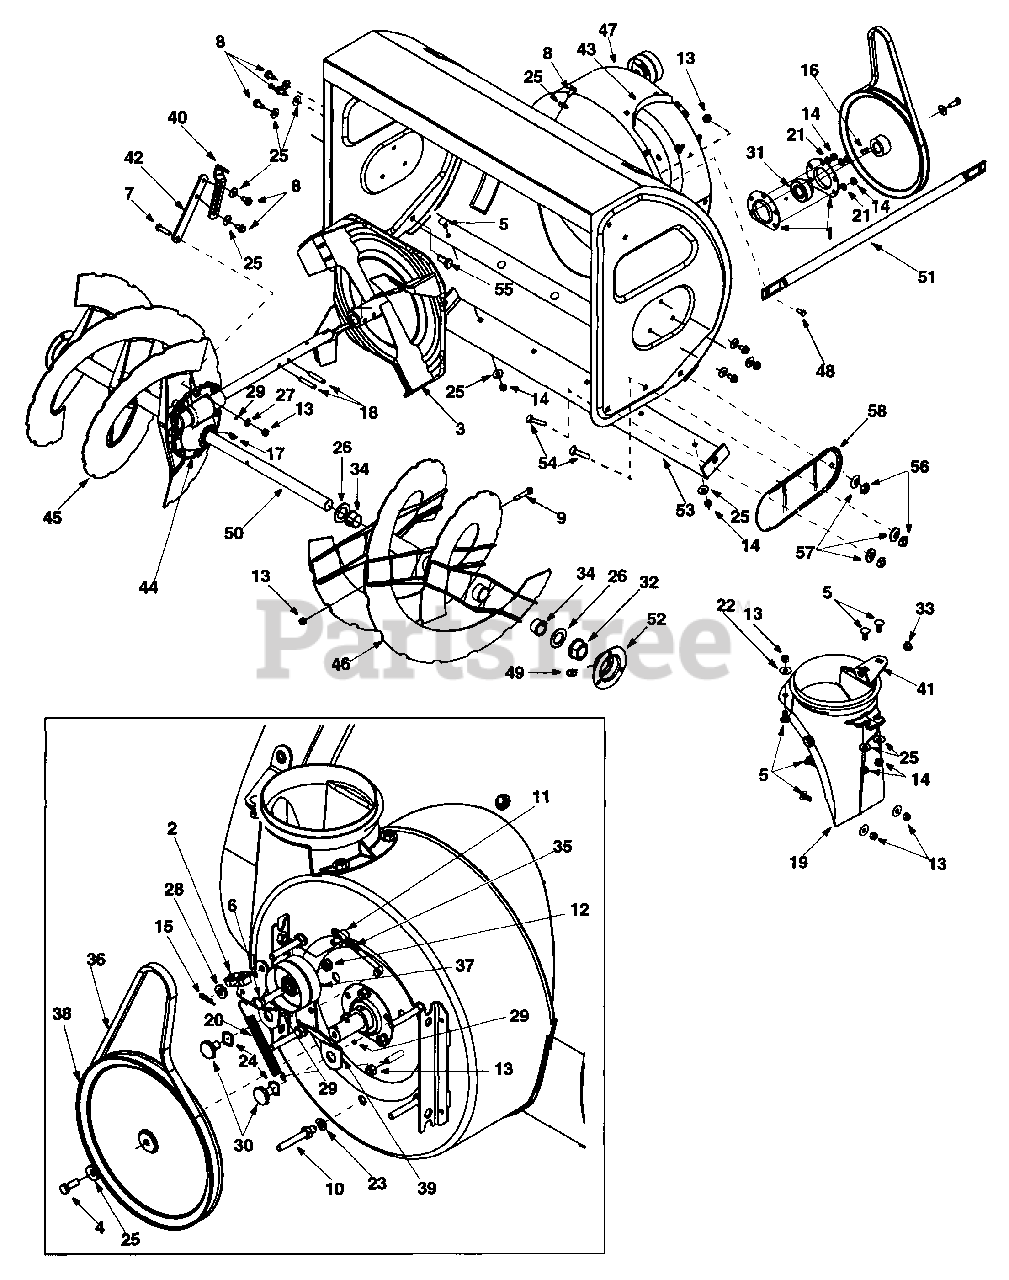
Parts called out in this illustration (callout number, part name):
1	Bearing Housing
2	Bracket Assembly: Auger Break
3	Impeller Assembly: 16"
4	Hex Lock Bolt 5/16-18 x .875"
5	Carriage Bolt 5/16-18 x .750"
6	Hex Screw, Special 3/8-24 x 1.5"
7	Hex Screw 5/16-18 x 1.25"
8	Self-Tapp. Screw 5/16-18 x .625"
9	Shear Bolt 5/16-18 x 1.75"
10	Stud
11	Ferrule
12	Jam Nut 3/8-24
13	Hex Lock Nut 5/16-18
14	Hex Nut 5/16-18
15	Hairpin Clip
16	Key
17	Key
18	Spiral Pin
19	Chute Adapter
20	Extension Spring
21	Lock Washer
22	5/16 Washer
23	Lock Washer
24	Wave Washer
25	Beleville Washer
26	Flat Washer
27	Spring Washer
28	Flat Washer
29	Grease
30	Shoulder Screw
31	Self-Aligning Bearing
32	Flange Bearing w/ Flats
33	Plastic Bushing
34	Flange Bushing
35	Idler Rod: Auger
36	V-Belt
37	Flat Idler
38	Pulley
39	Idler Bracket: Auger
40	Support Bracket
41	Chute Crank Bracket
42	Support Plate
43	Chute Bracket
44	Gear Assembly: Auger w/Grease Fitting
45	Spiral Assembly RH
46	Spiral Assembly LH
47	Auger Housing Assembly
48	Hex Screw 5/16-18 x .75"
49	Lube Fitting
50	Spiral Axle
53	Shave Plate
54	Carriage Screw
55	Carriage Bolt
56	Hex Nut 3/8-16
57	Bell Washer
